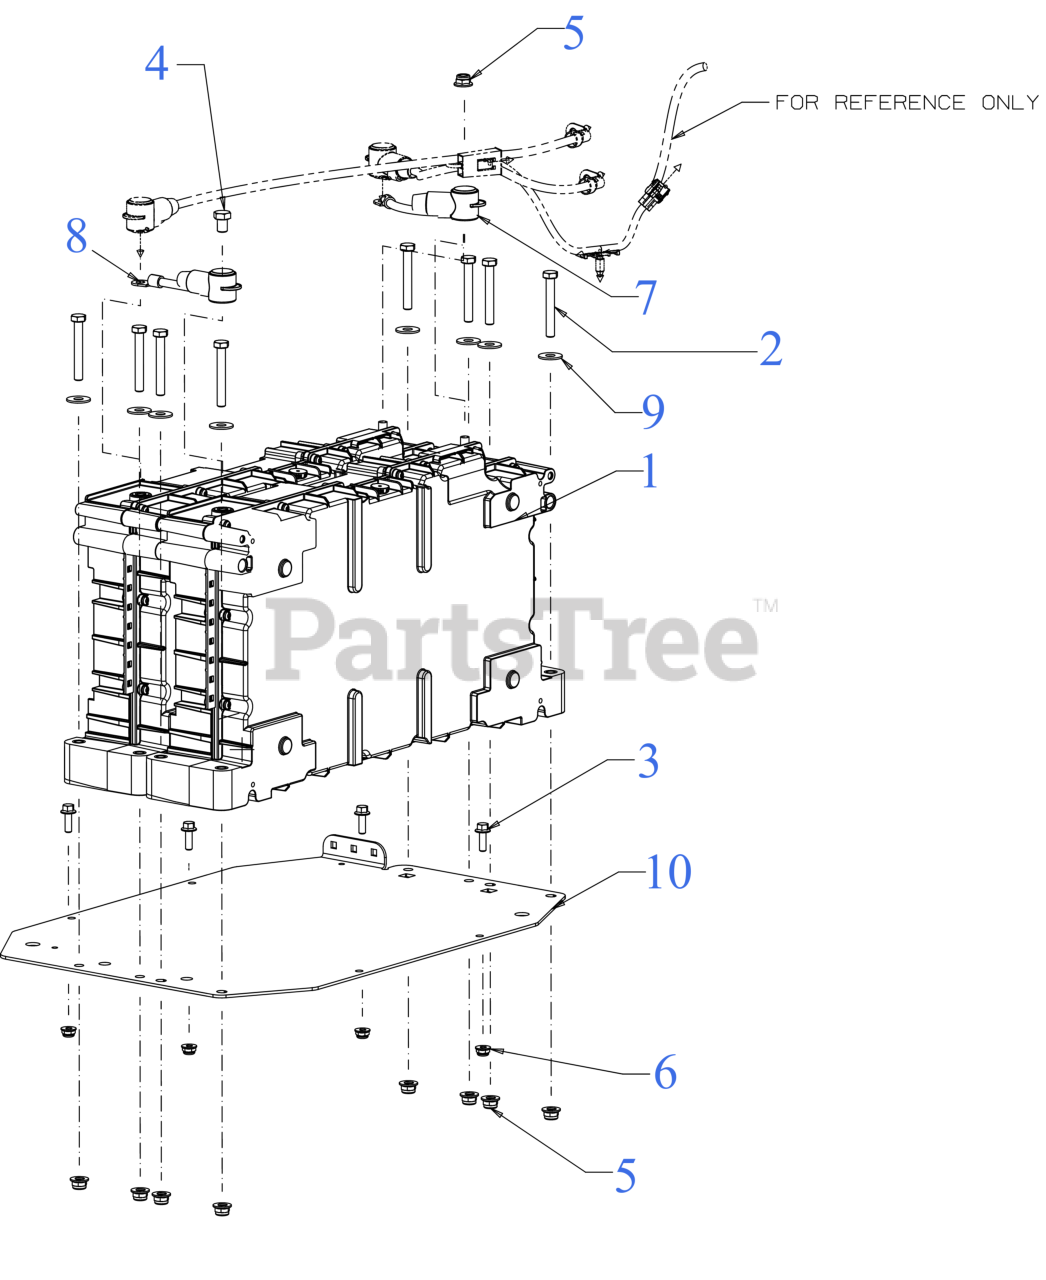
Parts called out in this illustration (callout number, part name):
2	HEX SCREW 5/16-18 x 2.25 GR5
3	SCREW 1/4-20 x .75 GR5
4	SCREW 3/8-24 x .50" GR5 STD
5	FLANGE LOCK NUT 5/16-18
6	FLANGE LOCK NUT
7	JUMPER BATTERY HARNESS
8	JUMPER BATTERY HARNESS
9	FLAT WASHER
10	BATTERY PLATE BRACKET
